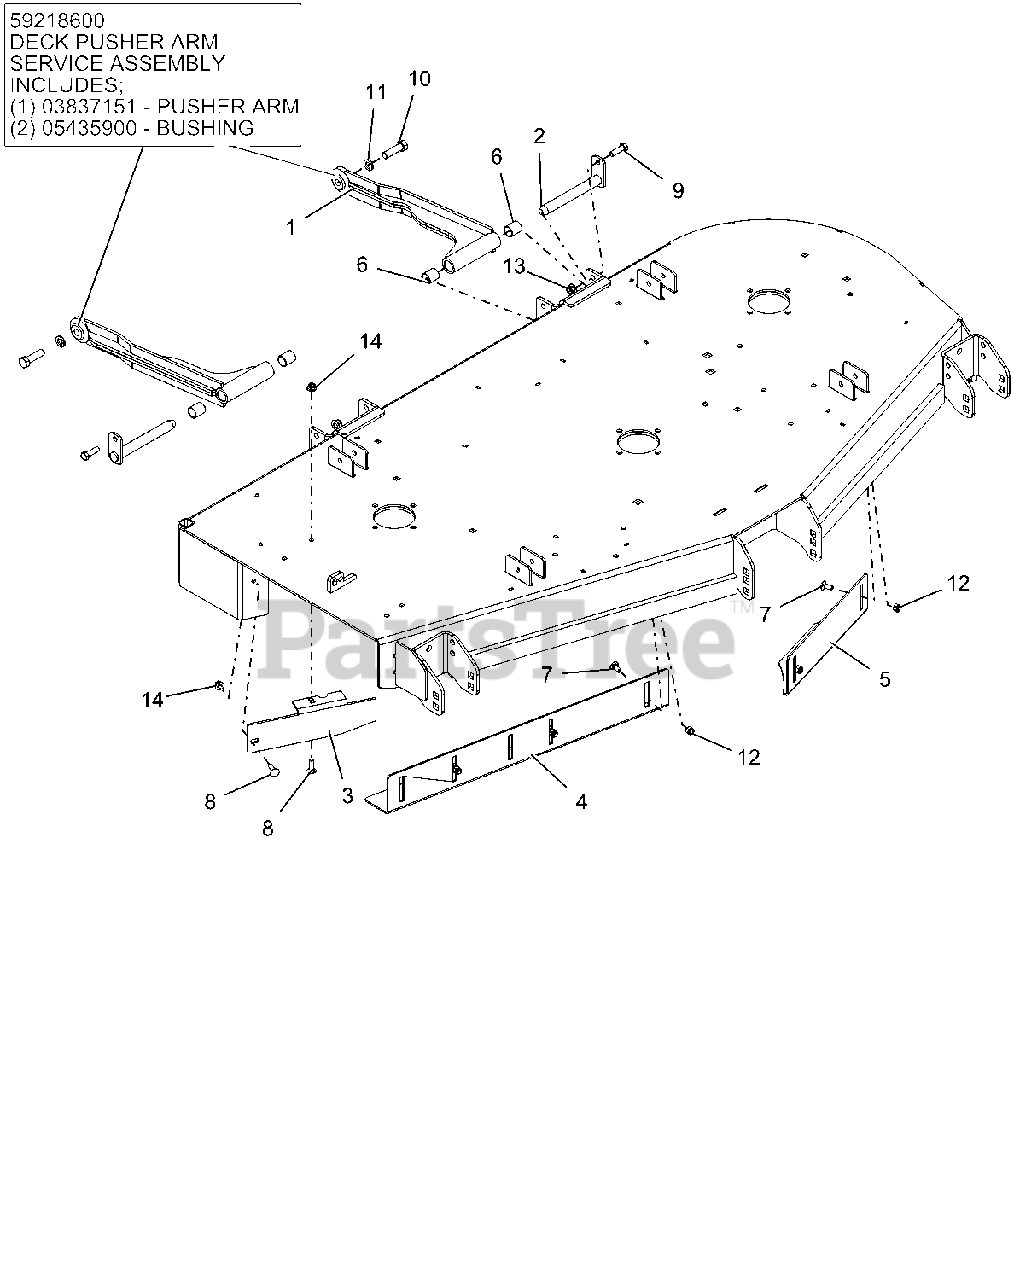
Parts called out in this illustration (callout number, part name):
1	BRG, .750 X .875 X 1.000
1	DECK STABILIZER ARM W/BUSHINGS
1	DECK STABILIZER ARM - BLACK
2	WELDMENT, MOWER MTG. PIN
3	60" DISCHARGE BAFFLE - RED
4	60" RH VACUUM BAFFLE - BLK
5	60" LH VACUUM BAFFLE - BLK
6	BRG, .750 X .875 X 1.000
7	@BLT-RDHDSQNK .31-18X.75 G5YZ
8	@BLT-RDHDSQNK .31-18X1.00 G5YZ
9	@BLT-HEX .38-16X1.25 GR5 YWZC
10	BLT-HEX .50-13X1.75 GR5EP80 YZ
11	@WSHR-LK .50X.125 REG YWZC
12	@NUT-LK-NYL .312-18 YWZC
13	@NUT-LK-NYL-FLG .38-16 YWZC
14	@NUT-LK-NYL-FLG .31-18 YWZC
